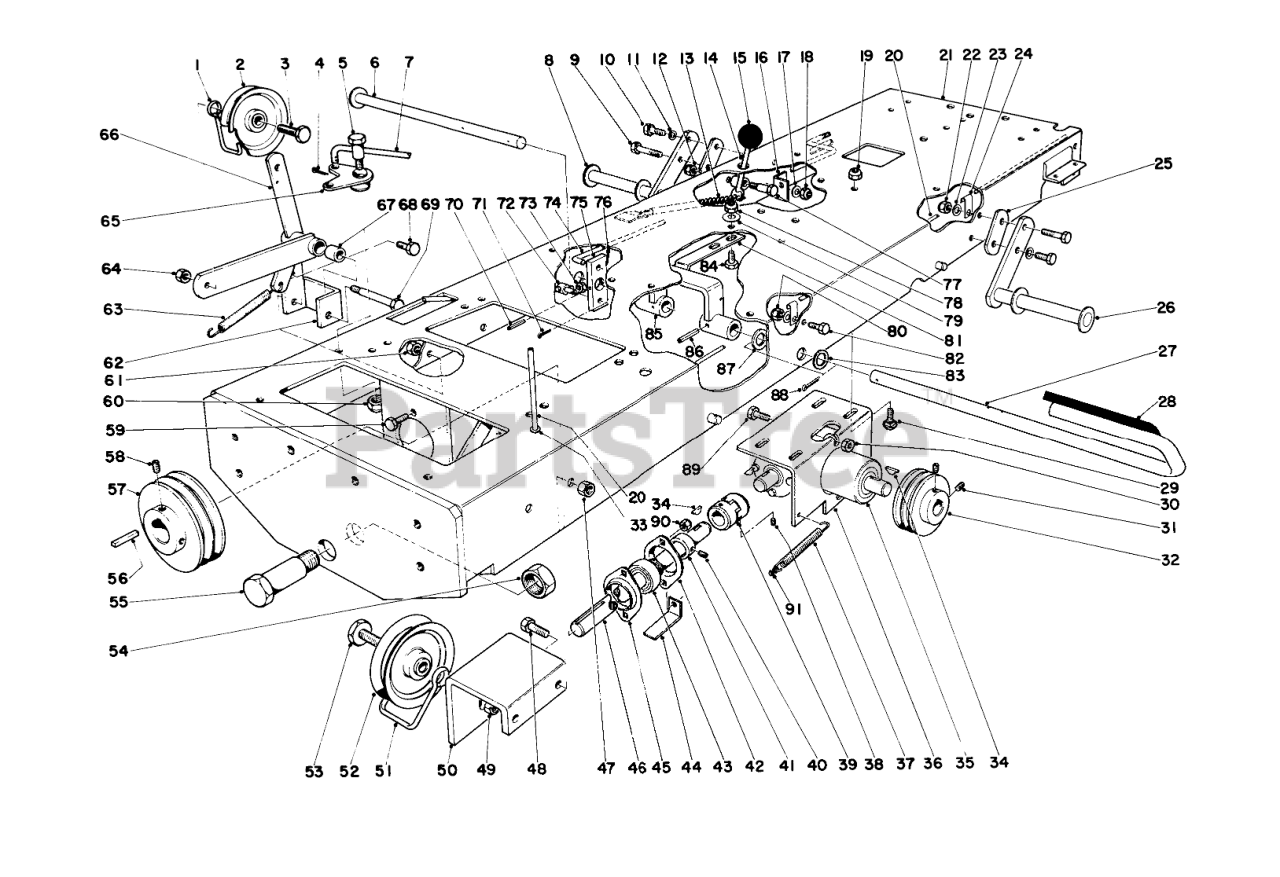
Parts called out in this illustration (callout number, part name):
1	Belt Retainer
2	IDLER PULLEY
3	3/8-16 X 1-1/2 BOLT
4	PIN-COTTER
6	Brake Shaft
7	Idler Rod
8	Bracket Foot Rest
9	SCREW-HH
10	SCREW-HH
11	WASHER-LOCK
12	NUT-LOCK, CONE
13	IDLER ARM SPRING
14	Brake Lock
15	KNOB-CONTROL
16	Brake Rod Retainer
17	WASHER-FLAT
18	NUT-LOCK, CONE
19	NUT-LOCK, CONE
20	Gas Line
21	Chassis 950
22	NUT-LOCK, CONE
23	WASHER-FLAT
25	Spacer Foot Rest
26	Bracket Foot Rest
27	Brake Crank Arm
28	PAD-BRAKE
29	BOLT-CARR
30	NUT-LOCK, CONE
31	SCREW-SET
32	Pulley Drive
33	NYLINER #7L2FF TYPE 7
34	KEY-WOODRUFF
35	Gear Box
36	Bracket Right Angle Gear Box
37	Spring
38	SCREW-SET
39	Coupling
40	SCREW-SET, HSH
41	Collar
42	Bearing Flange
43	Bearing
44	Belt Guide
45	Bearing Incl. Ref. 41-43
46	Drive Shaft
47	NUT-LOCK, CONE
48	SCREW-HH
49	NUT-LOCK, SIDE
50	Idler Bracket
51	Belt Retainer
52	IDLER PULLEY
53	3/8-16 X 1-1/2 BOLT
54	NUT-LOCK, CONE
55	Pivot Bolt
57	Pulley Drive
58	SCREW-SET, HSH
59	Screw
60	NUT-JAM
61	NUT-LOCK, CONE
62	Mounting Bracket Idler
63	Spring
64	NUT-LOCK, SIDE
65	Bell Crank
66	Idler Arm Incl. Ref. No. 67
67	Bushing
68	Capscrew
69	Shoulder Bolt
70	PIN-SPRING
71	PIN-COTTER
72	Pivot Clutch Rod
74	Brake Rod
75	Bracket Idler
76	PIN-COTTER
78	NUT-LOCK, CONE
79	WASHER-FLAT
80	NUT-LOCK, CONE
81	Stop Brake Pedal
82	SCREW-HH
83	Washer
84	Screw
85	Bracket Assy.
86	PIN-SPRING
87	Washer
88	PIN-COTTER
89	SCREW-HH
90	NUT-LOCK, CONE
91	S-Hook
